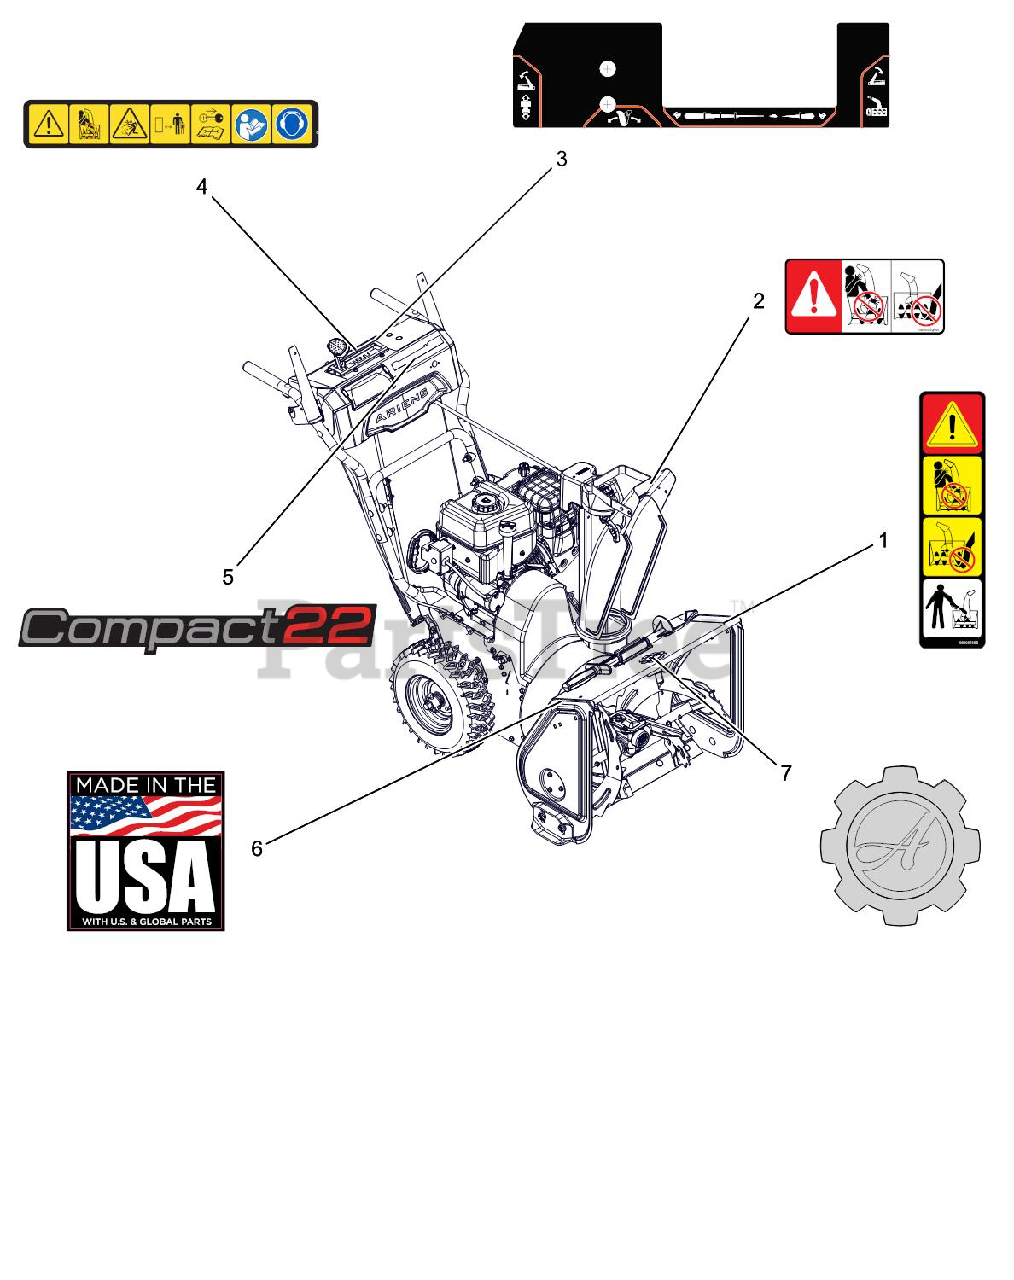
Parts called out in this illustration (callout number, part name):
1	DECAL, DANGER - ROTATING PARTS
2	DECAL, DANGER
3	DECAL,CONTROL-COMP MAN
4	DECAL,DASH - SAFETY
5	DECAL, DASH - COMPACT 22
6	DECAL, MADE IN USA
7	DECAL, ARIENS-GEAR BADGE
